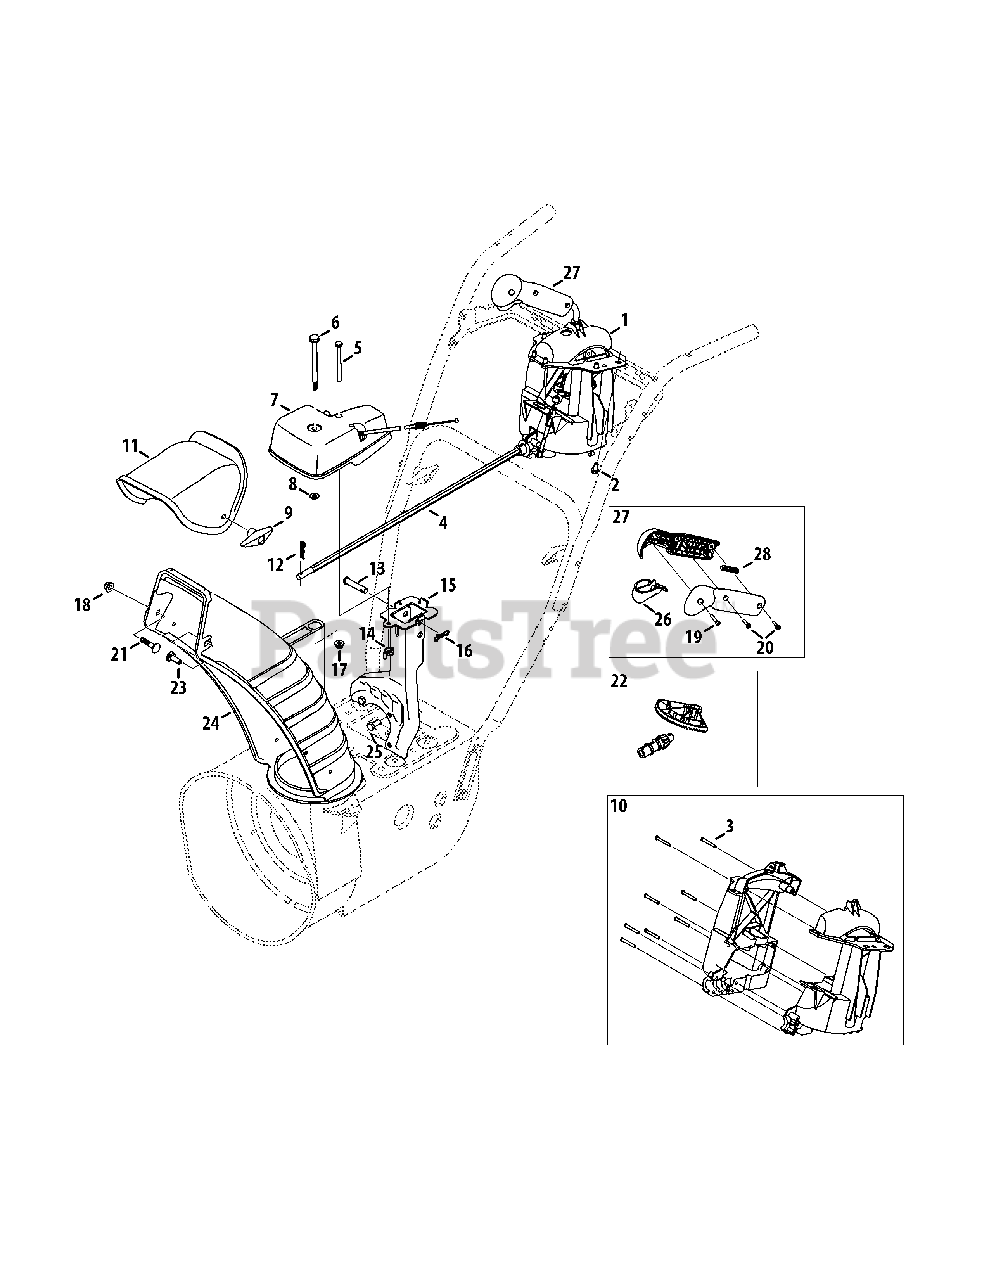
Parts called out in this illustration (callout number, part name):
1	2-Way Chute Control Assembly
2	Hi-Lo Screw, 1/4-15 x 0.5
3	Screw, #8-18 x 1.250
4	Chute Rod
5	Hex Screw, 1/4-20 x 3.00
6	Flange Shoulder Screw
7	Gearbox Assembly
8	Flat Washer, .25 x .630 x .0515
9	Wing Knob
10	Handle Housing Assembly
11	Upper Chute
12	Cotter Pin
13	Clevis Pin
14	Wing Nut, 1/4-20
15	Chute Support Bracket
16	Bow Tie Cotter Pin
17	Flange Lock Nut, 1/4-20
18	Flange Lock Nut, 5/16-18
19	Screw, #8 x 1.00
20	Screw, Mach., #8-32 x .750
21	Carriage Bolt, 5/16-18 x .75
22	Gear Set Assembly
23	Carriage Bolt, 5/16-18 x 1.0
24	Lower Chute
25	Hex Screw, 5/16-24 x .750
26	Handle Lever
27	Handle Assembly
28	Handle Plunger
